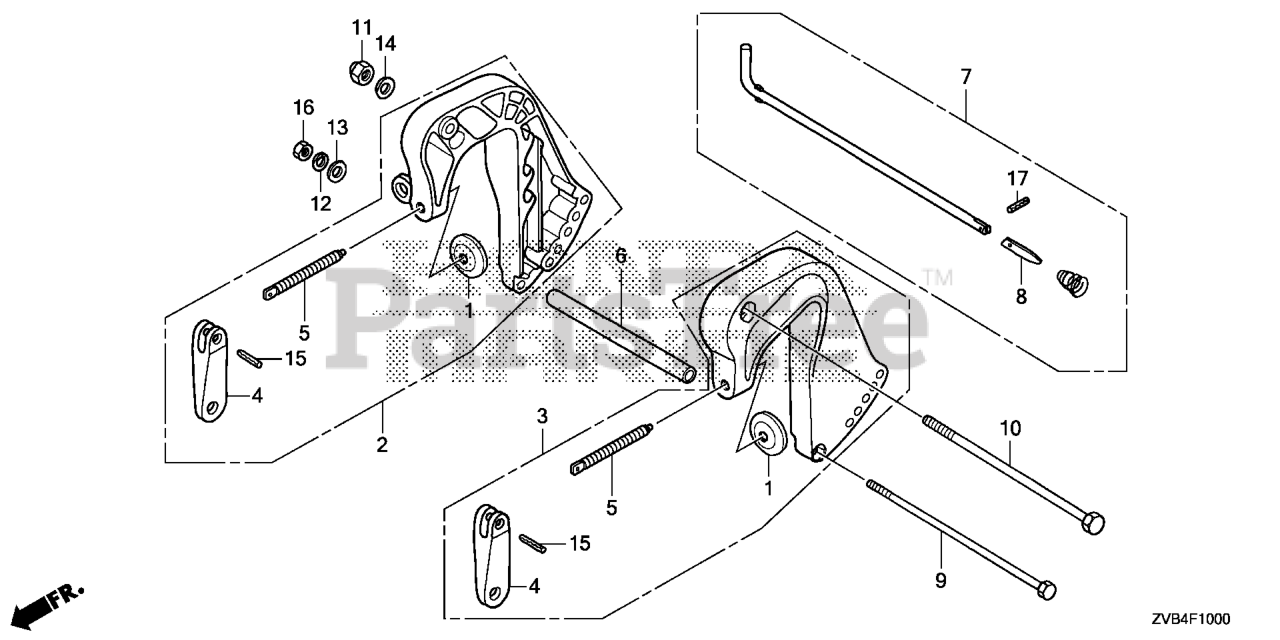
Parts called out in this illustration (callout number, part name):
1	PLATE, PUSH
2	BRACKET, R. STERN *NHB14M* (AQUA MARINE SILVER METALLIC)
3	BRACKET, L. STERN *NHB14M* (AQUA MARINE SILVER METALLIC)
4	GRIP, CLAMP
5	SCREW, CLAMP
6	COLLAR, DISTANCE (6MM)
7	ROD, ADJUSTING
8	STOPPER, ROD
9	BOLT, HEX. (6X140)
10	BOLT, HEX. (8X130)
11	NUT, SELF-LOCK (8MM)
12	WASHER, SPRING (6MM)
13	WASHER, PLAIN (6MM)
14	WASHER, PLAIN (8MM)
15	RIVET (4X22.6)
16	NUT, HEX. (6MM)
17	PIN, SPRING (2X6)
